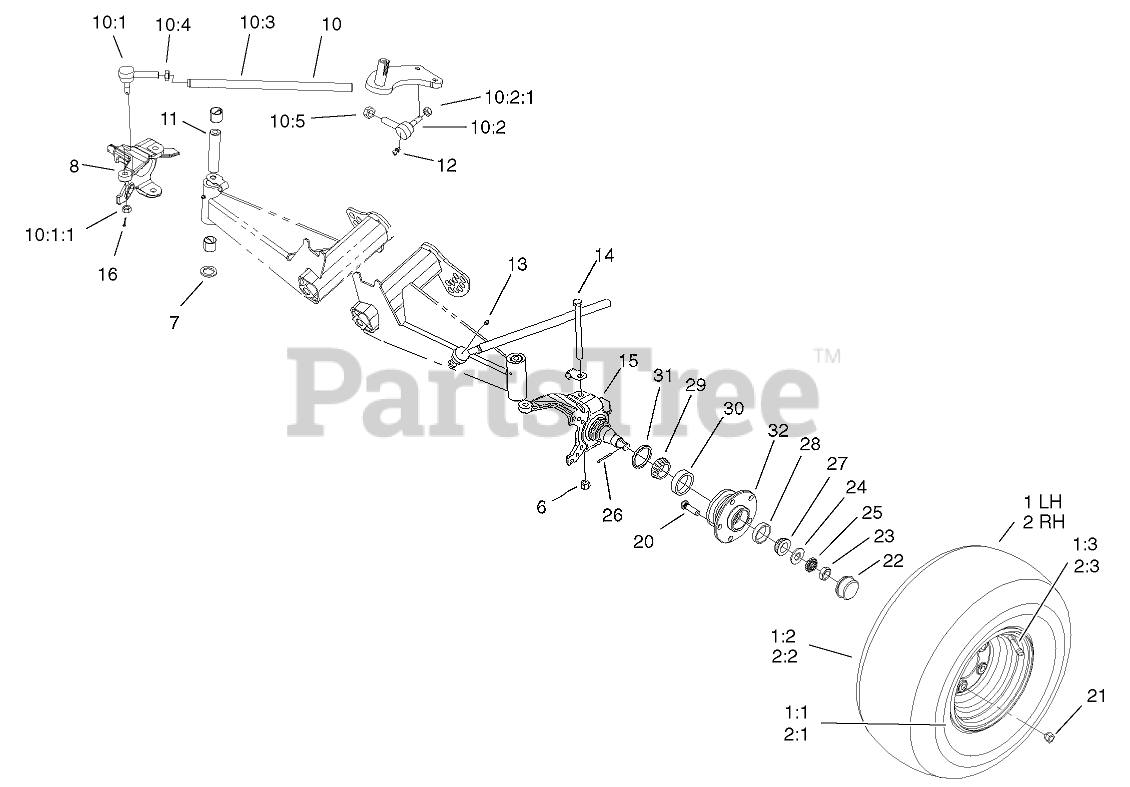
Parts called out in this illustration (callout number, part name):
1	TIRE AND WHEEL ASM
1:1	WHEEL-5 BOLT
1:3	STEM-VALVE
2	TIRE AND WHEEL ASM
2:1	WHEEL-5 BOLT
2:3	STEM-VALVE
6	NUT-LOCK, NI
7	WASHER-THRUST
8	SPINDLE-DISC, RH
10	Rod-Tie
10:1	SOCKET-BALLJOINT
10:2	SOCKET-BALLJOINT
10:3	ROD-TIE
10:4	NUT-JAM
10:5	NUT-JAM
11	SLEEVE-KINGPIN
12	FITTING-GREASE
13	FITTING-GREASE
14	SCREW-HH
15	SPINDLE-DISC, LH
16	PIN-COTTER
20	STUD-TYPE, DRIVE
21	NUT-LUG
22	CAP-DUST
23	NUT-JAM
24	WASHER-TAB
25	NUT-LOCK, RETAINER
26	PIN-COTTER
27	BEARING-CONE, TAPERED
28	BEARING-CUP, TAPERED
29	CONE-BEARING, TAPERED
30	CUP-BEARING, TAPERED
31	SEAL-BEARING
32	HUB
